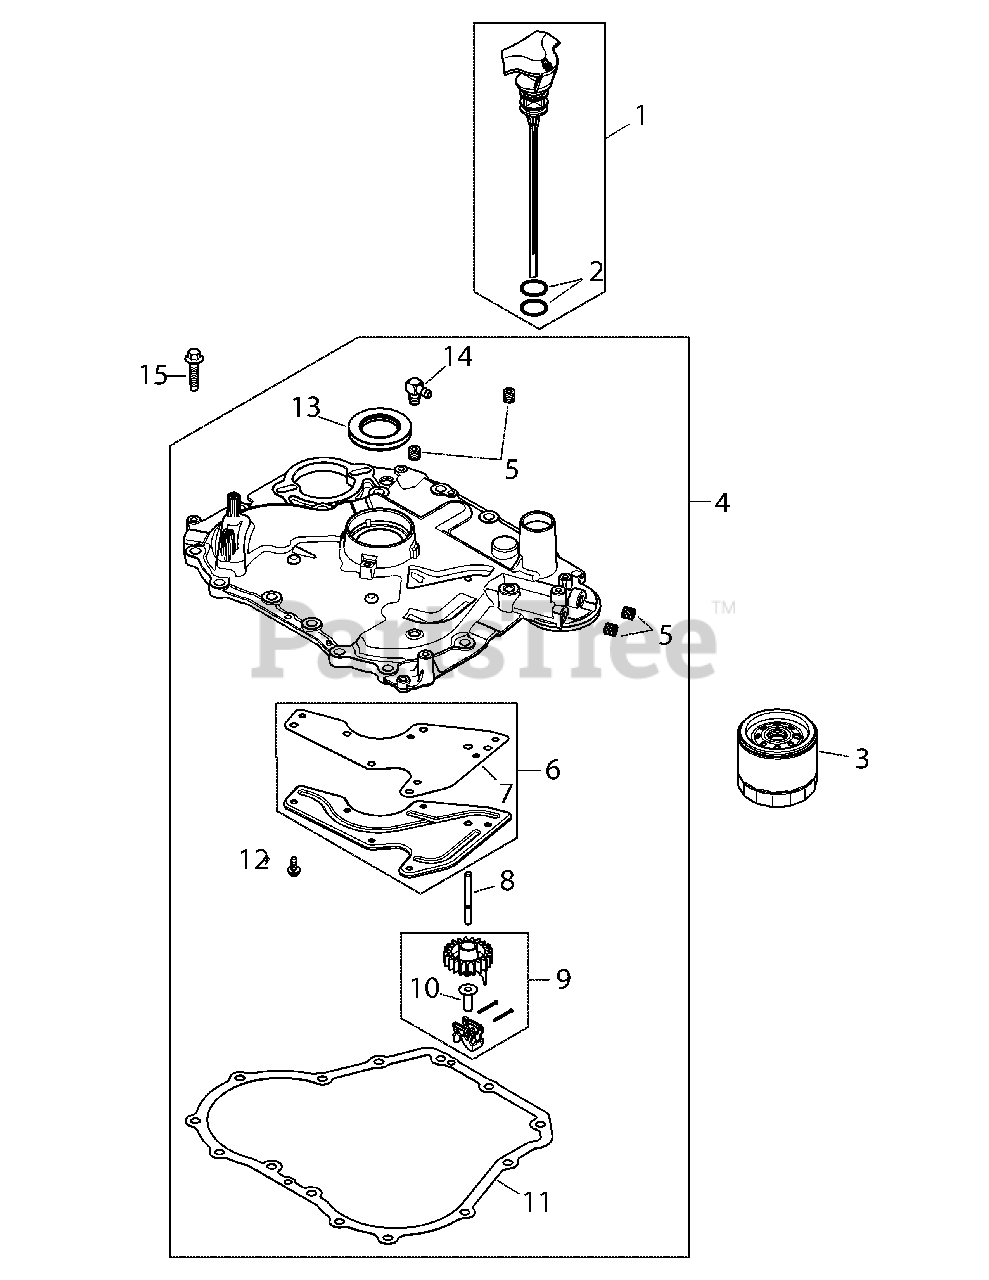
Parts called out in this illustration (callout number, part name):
1	Dipstick Ass’y-Std Yellow (Incl. 2)
2	O-Ring
4	Closure Plate Assembly (Incl. 5-14)
5	Ctsk Pipe Plug, 1/8
6	Oil Passage Cover Kit (Incl. 7)
7	Oil Passage Gasket
8	Governor Cross Shaft
9	Governor Gear Assembly
10	Governor Regulating Pin
11	Closure Plate Gasket
12	Flange. Thd. Frm. Screw, M5 X 0.8
13	Oil Seal
14	90° Hose Connector
15	Hex Flange Screw, 1/2
